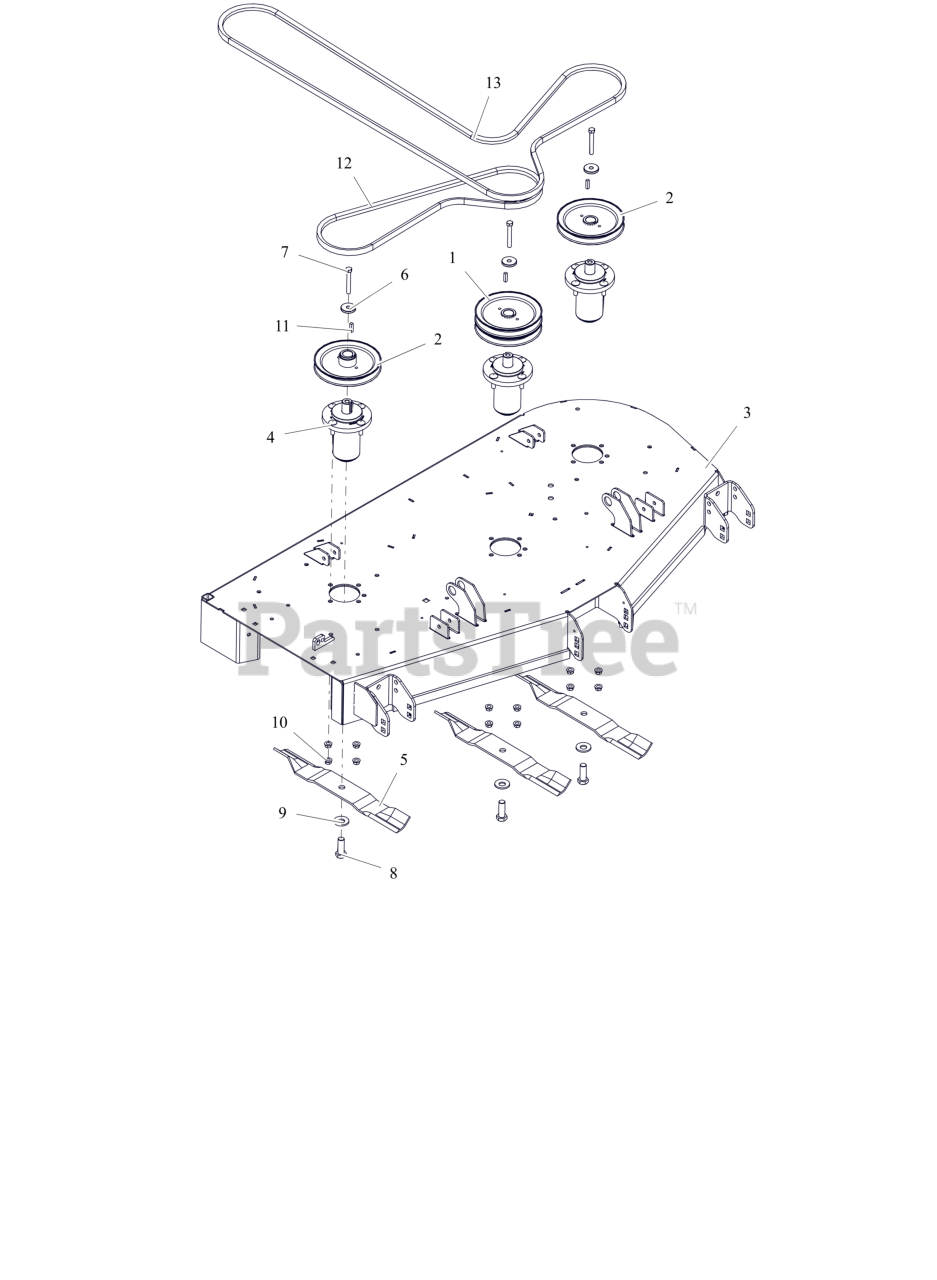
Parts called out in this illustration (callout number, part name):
1	PULLEY, DOUBLE-1"ID X 6.75"OD
2	PULLEY, V-1" ID X 6.75" OD
3	WLDMT, 52 SIDE DISCH DECK CE (ORANGE)
4	ASM, MAINT FREE ALUM SPINDLE
5	BLADE, 18"
6	RETAINER, SHEAVE
7	BLT, HEX .38-16X2.75 G8 ZCC
8	BLT, HEX .62-18X1.75 G8 ZCC
9	WSHR-BLVL .669X1.535X.138
10	NUT-LK-CTR-FLG .375-16 GF ZCC
11	KEY, SQ .25X.25X1.00 RC 40-50
12	V-BELT, B-COGGED
13	V-BELT, HB SECTION
